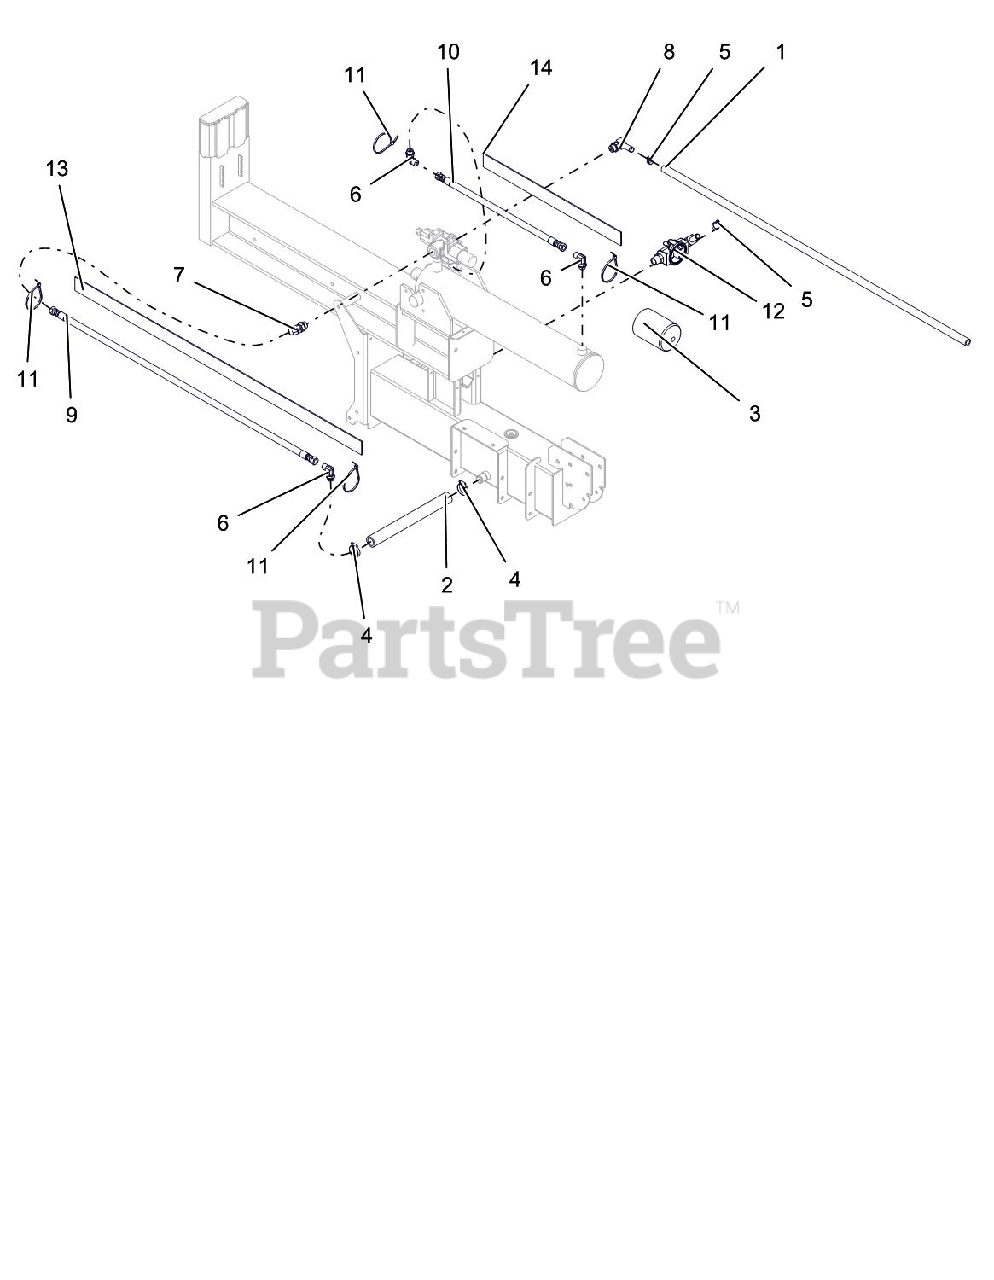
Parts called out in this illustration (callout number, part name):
1	HOSE,HYD RETURN 10LOLA X 53"
2	HOSE,HYD SUCTION 16G4H X 13.5
3	FILTER,HYDRAULIC OIL-NO BYPASS
4	CLAMP-HOSE 1.50X.81X1.42
5	CLAMP,.88 DIA. HOSE
6	FTG,HYD 6801-8-8
7	FTG,HYD 6802-8-10
8	FTG,HYD 4601-10-10
9	HOSE, ASM - 46"
10	HOSE, HYD - 22"
11	CABLE TIE LG 5-1/2
12	ASM, FILTER HEAD
13	SLV, PROTECTIVE - 50"
14	SLV, PROTECTIVE - 24"
